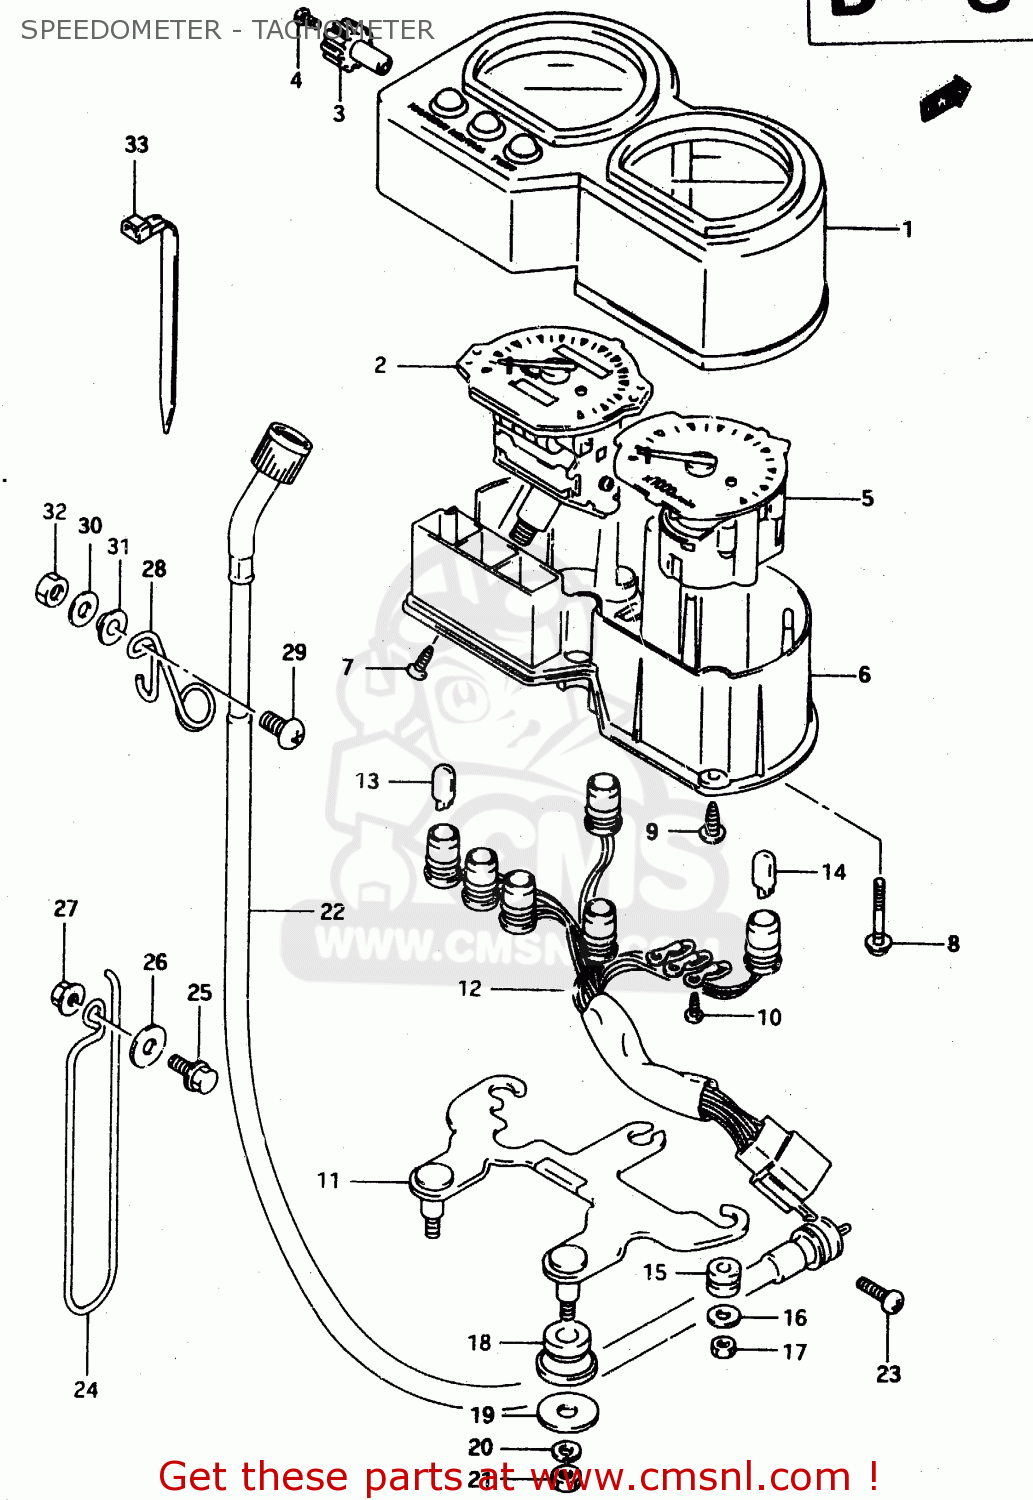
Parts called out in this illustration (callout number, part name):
1	VISOR
2	SPEEDOMETER(KILO)
3	KNOB
4	SCREW(2X6)
5	TACHOMETER
6	CASE,METER
7	SCREW
8	SCREW (4X36)
9	SCREW
10	SCREW
11	BRACKET
12	SOCKET,METER
13	BULB(12V3.4W,T10)
14	BULB(12V1.7W,T10,WB121)
15	CUSHION
16	WASHER (5.5X16X1.2)
17	NUT
18	CUSHION,METER BRACKET
19	WASHER (8.5X20X1.6)
20	LOCK WASHER
21	NUT
22	CABLE ASSY,SPEEDOMETER
23	SCREW
24	GUIDE,METER CABLE NO.2
25	BOLT
26	WASHER(6.5X20X1.6)
27	NUT
28	GUIDE,METER CABLE NO.3
29	SCREW
30	WASHER
31	WASHER
32	NUT 6MM
33	CLAMP(L:125)
